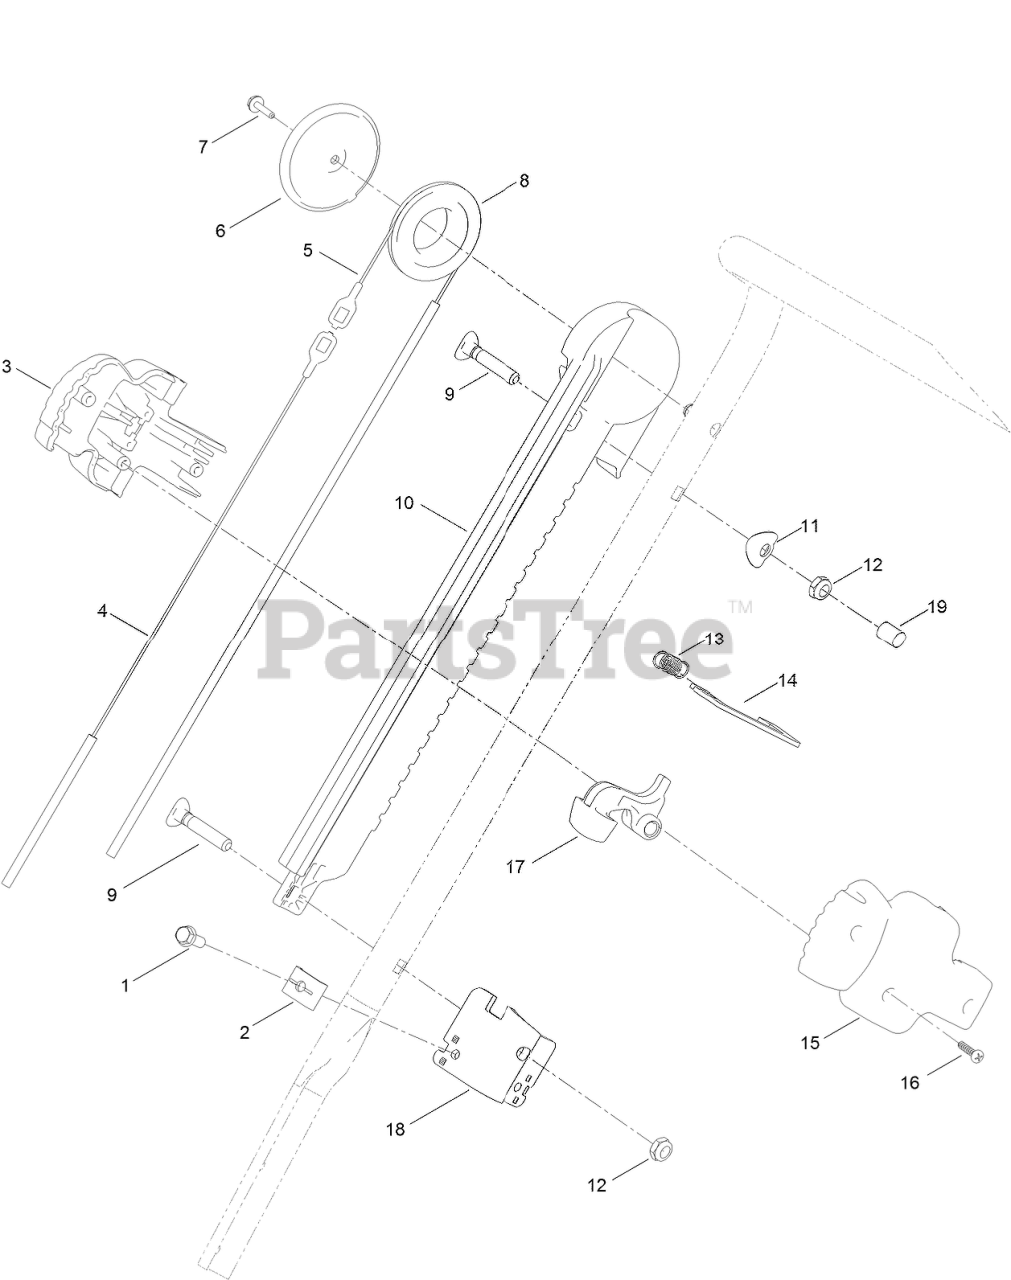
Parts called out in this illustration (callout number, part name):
1	SCREW-HWH
2	CLAMP-CABLE
3	HANDLE-SLIDER, RH
4	CABLE-CHUTE, SHORT
5	CABLE-CHUTE, LONG
6	COVER-PULLEY
7	SCREW-HWH
8	PULLEY-SLIDER
9	SCREW-HANDLE
10	TRACK-SLIDER
11	WASHER
12	NUT-LOCK, NI
13	SPRING-TRIGGER
14	LOCK PLATE-CHUTE
15	HANDLE-SLIDER, LH
16	SCREW-PPH
17	TRIGGER
18	BRACKET-CABLE
19	CAP-THREAD, SCREW
